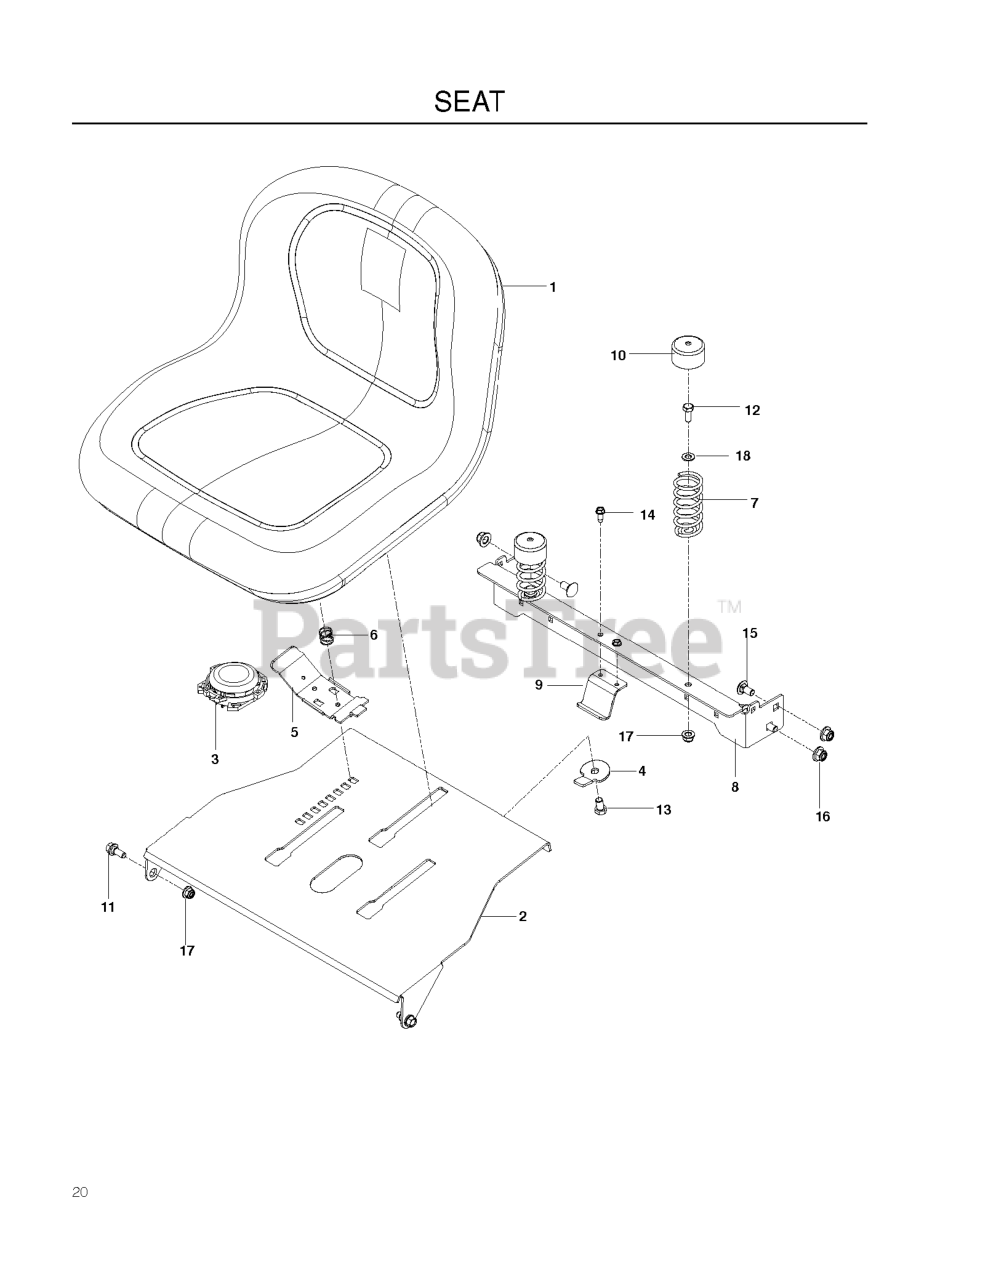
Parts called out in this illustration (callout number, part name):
1	RP SEAT, TH150, GREY, MILSCO
2	PLATE, SEAT, ORG
3	SWITCH, SEAT N/C
4	STOP, SEAT, BLACK
5	HANDLE.SLIDE.SEAT.TEX.BLACK
6	SPRING.LATCH.SEAT.TEX
7	SEAT SPRING
8	SEAT SUPPORT, REAR ORG
9	HOLDING DEVICE, FUEL TANK, BLK
10	SPRING CAP
11	BOLT, SHOULDER
12	HCS 5/16C X 3/4
13	HCS 3/8-16 X 5/8 GR 5 ZD
14	SCREW 1/4 X 5/8
15	RHSNB 3/8-16 X 3/4 GR5 ZD
16	NUT 3/8-16 HEX FLG NYLOC ZD
17	5/16-18 NYLOC FLANGE NUT
18	FLAT WASHER 5/16 SAE
